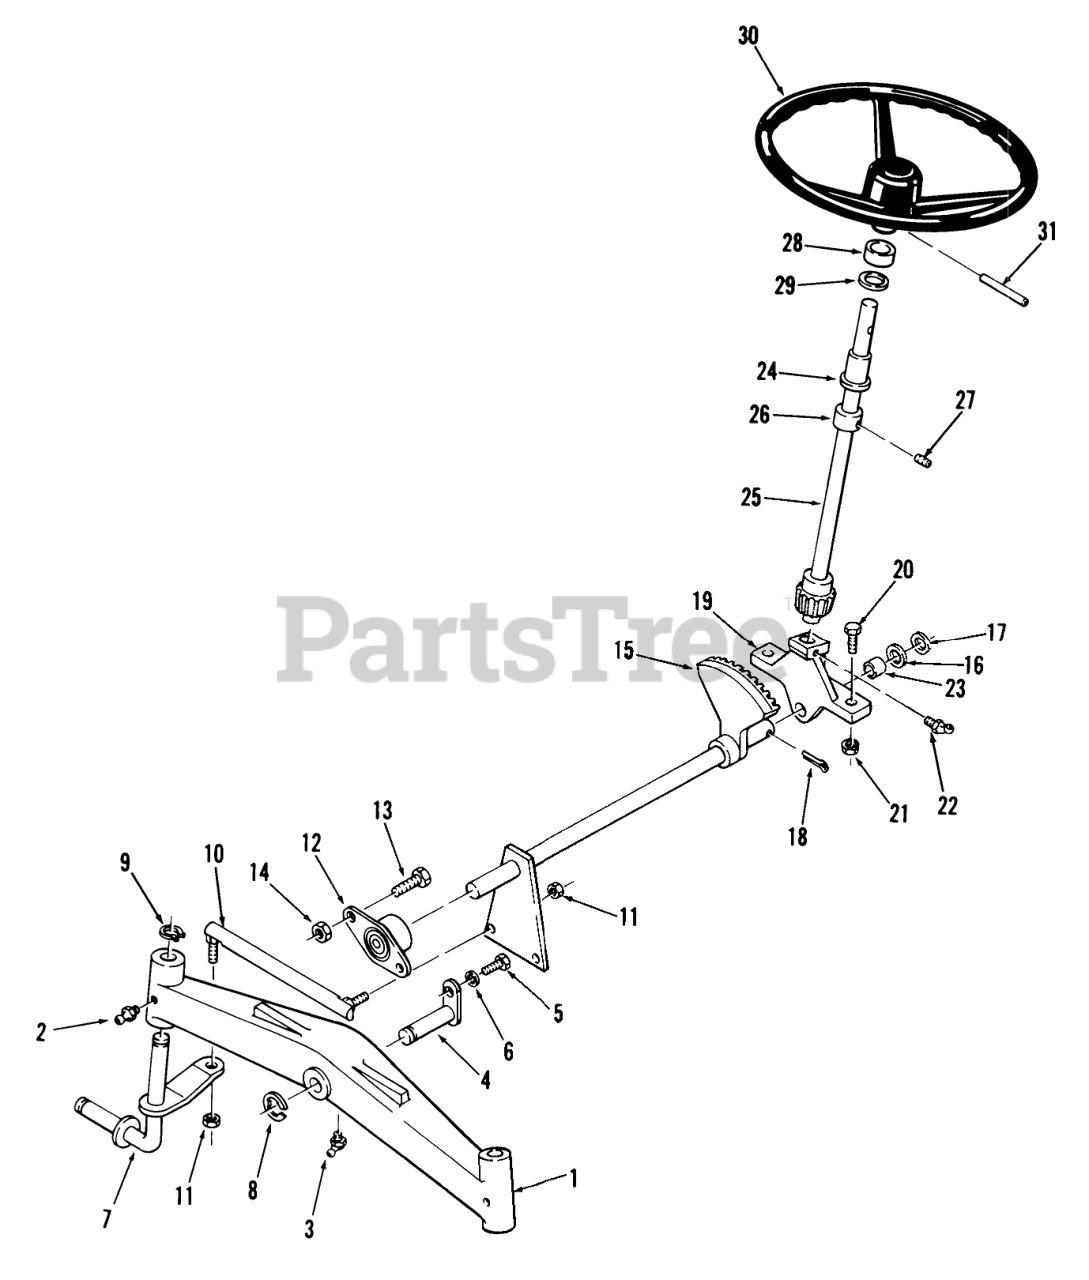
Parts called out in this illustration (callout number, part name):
1	AXLE-FRONT
2	Zerk
3	FITTING-GREASE
4	PIN AND PLATE ASM
5	H H C S
6	Lockwasher
7	Front Spindle RH
7	Front Spindle LH
8	E-RING
9	Snap Ring
10	Tie Rod RH
10	Tie Rod LH
11	NUT-6
12	BEARING-FLANGED
13	Bolt
14	Nut
15	Assy-Steering
16	WASHER-SHIM
17	WASHER
18	PIN-4
19	Support
20	Bolt
21	Nut
22	FITTING-GREASE
23	BEARING-BRONZE
24	BEARING
25	Shaft-Upper Steering
26	Collar
27	SCREW-SET
28	Collar
29	WASHER-BOWED
30	STEERING WH 13" PLAS
31	Pin-Roll
